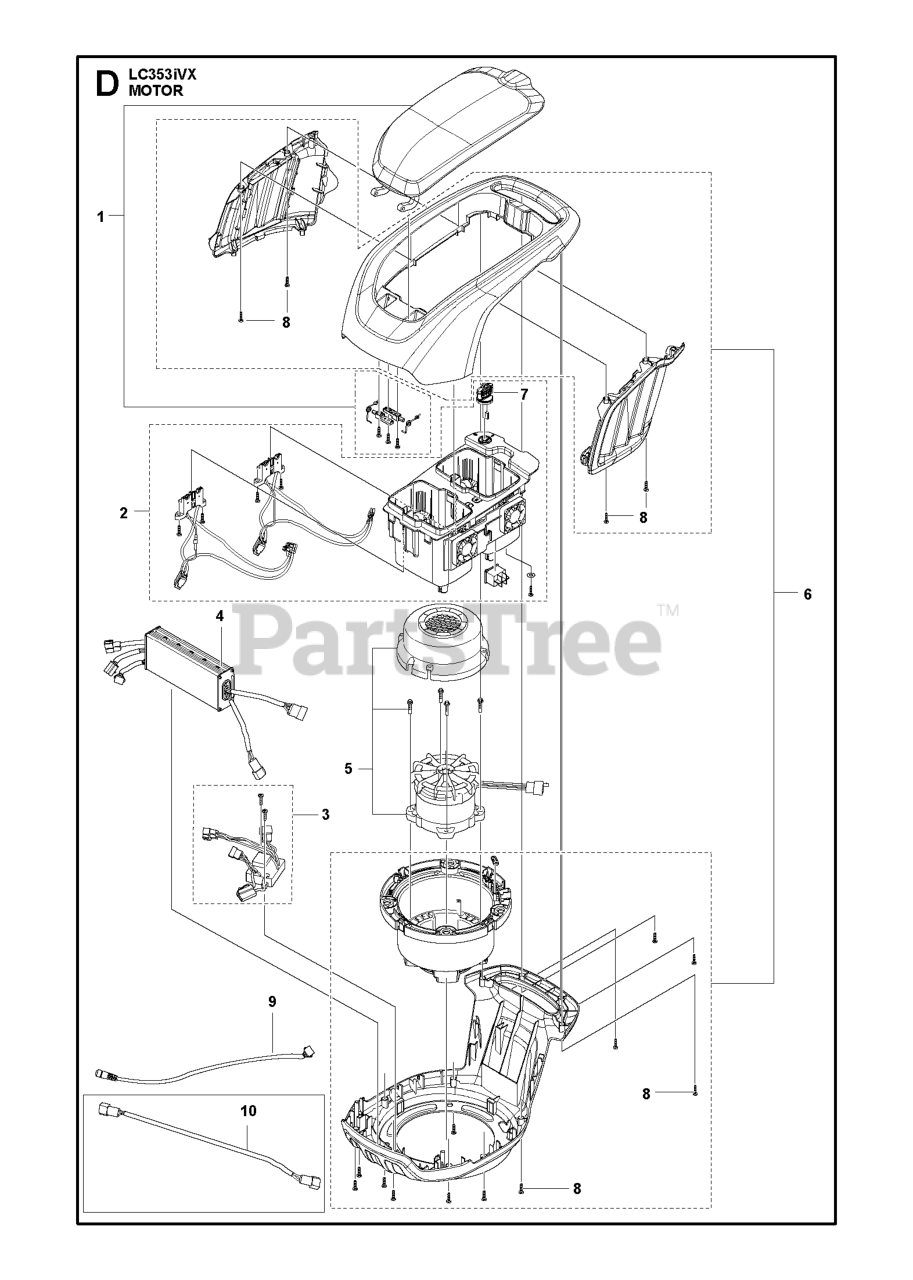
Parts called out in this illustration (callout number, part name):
1	LID ASSY SPARE PART ASSY LC247
6	ENGINE HOOD ASSY POWER UNIT LC
7	KEY
8	SCREW SELF TAPPING DAYE# A2680
10	CABLE TRANSMISSION LC347VLI
